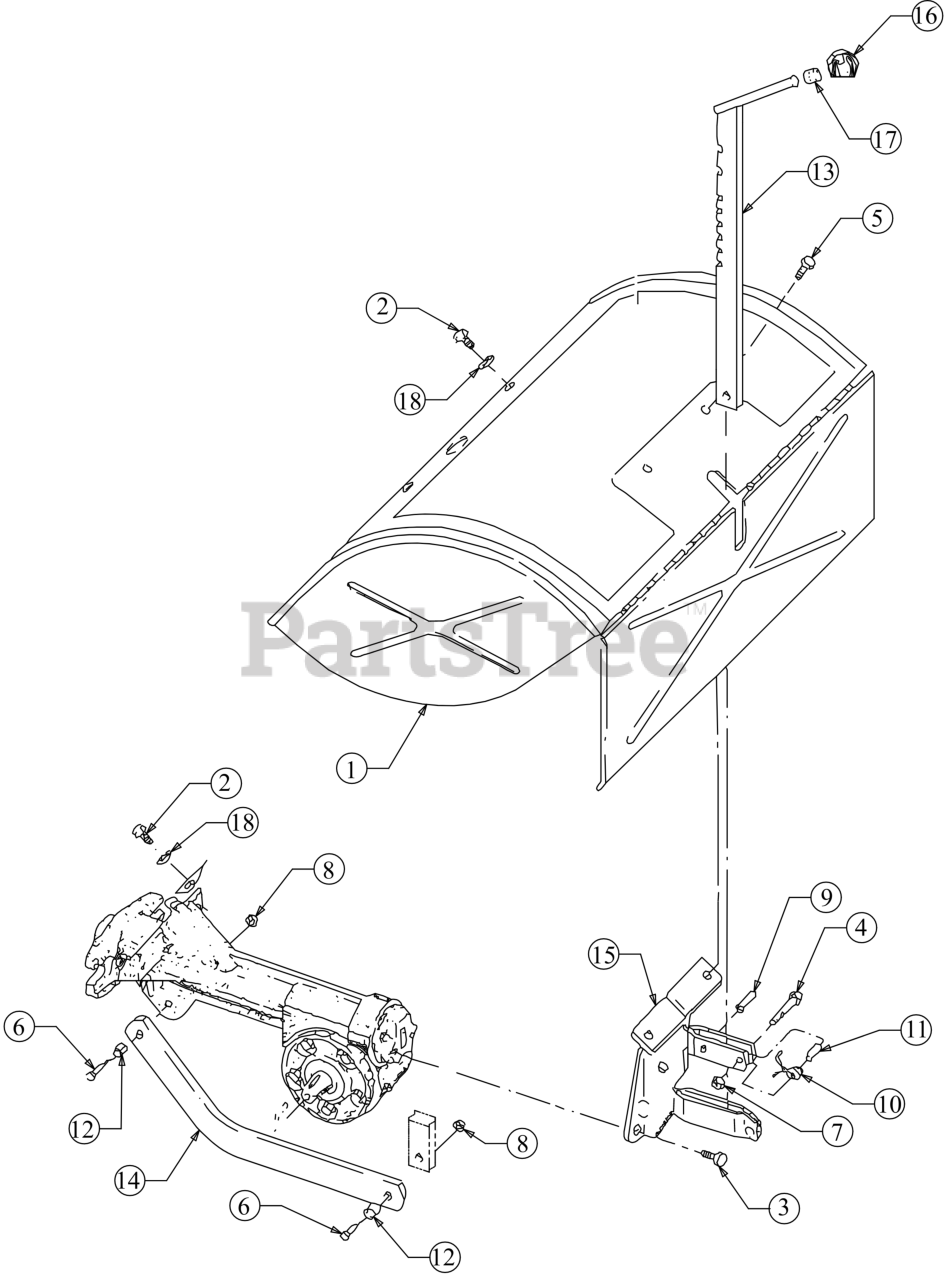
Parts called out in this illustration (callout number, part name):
1	TINE HOOD ASSEMBLY
2	SCREW 5/16-18
3	HEX SCREW 5/16-18 X .625 GR5
4	SCREW 1/4-20 X1.00 GR5
5	SCREW 1/4-20 X.500
6	SCREW 3/8-16 X 1.25 GR5
7	FLANGE LOCK NUT
10	TORSION SPRING
11	SPLIT SPACER
12	BUSHING .5 X
13	BAR DEPTH REGULATOR
14	DEPTH REGULATOR
15	BRACKET-HOOD
16	CONTROL KNOB
17	RING-TOLERANCE
18	WASHER-#1.125X.344
